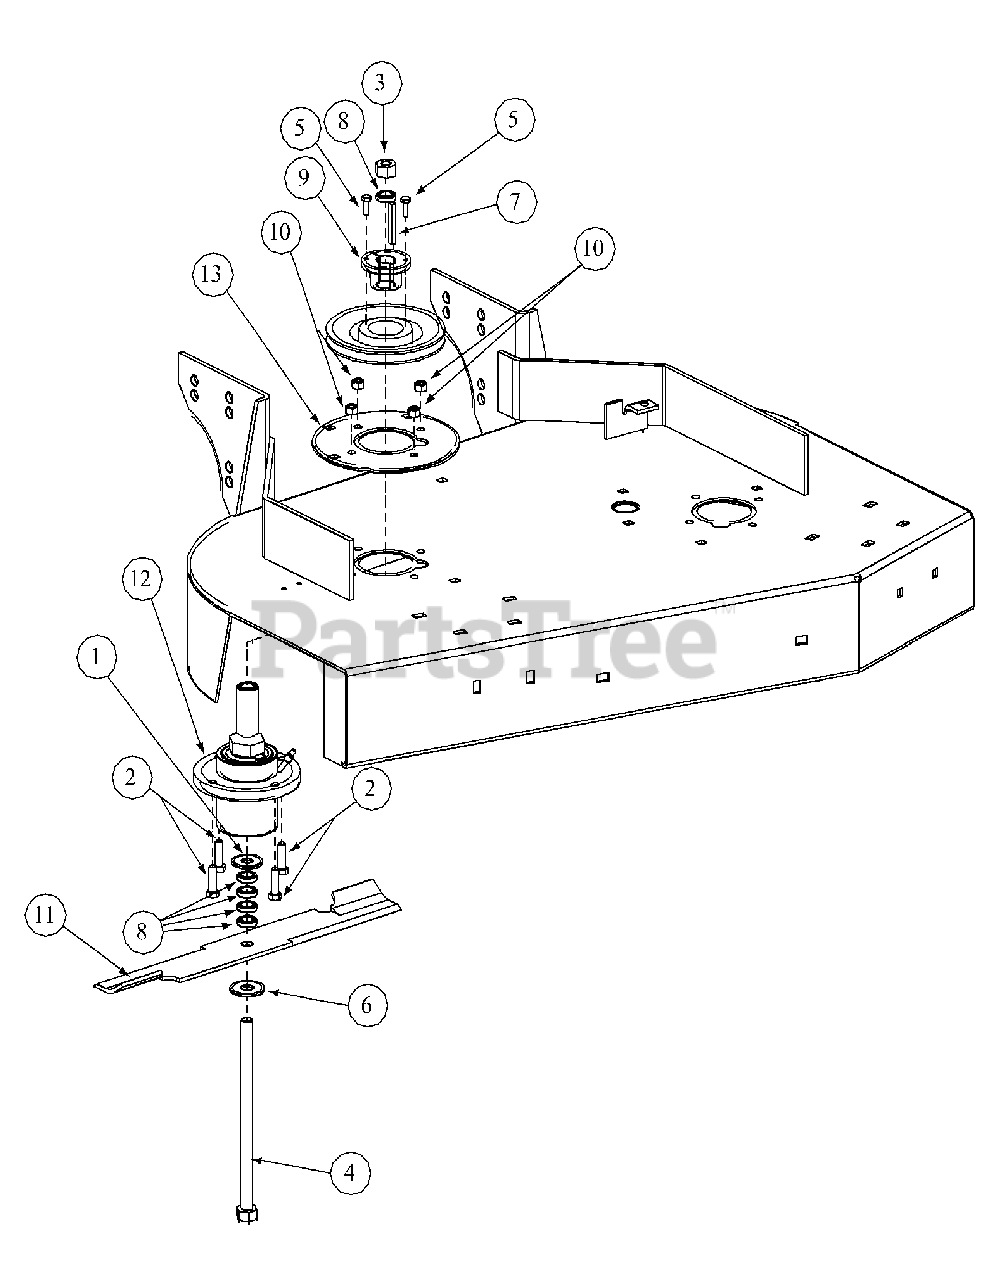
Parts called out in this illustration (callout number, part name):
1	Flat Washer, 1-1/2 x 5/8 x .05
2	Hex Cap Screw, 3/8-16 x 1-1/4
3	Hex Nut, 5/8-11
4	Hex Cap Screw, 5/8-11 x 9-1/2
5	Hex Cap Screw, 1/4-20, .75
6	Flat Washer, 5/8 Zinc
7	Key Stick, 1/4 x 1/4 x 2
8	Blade Spacer, 5/8 ID, 1/4 Thick
9	Bushing
10	Lock Nut, 3/8-16
11	Blade 18"
12	Spindle Assembly
13	Plate, Spindle Backing
